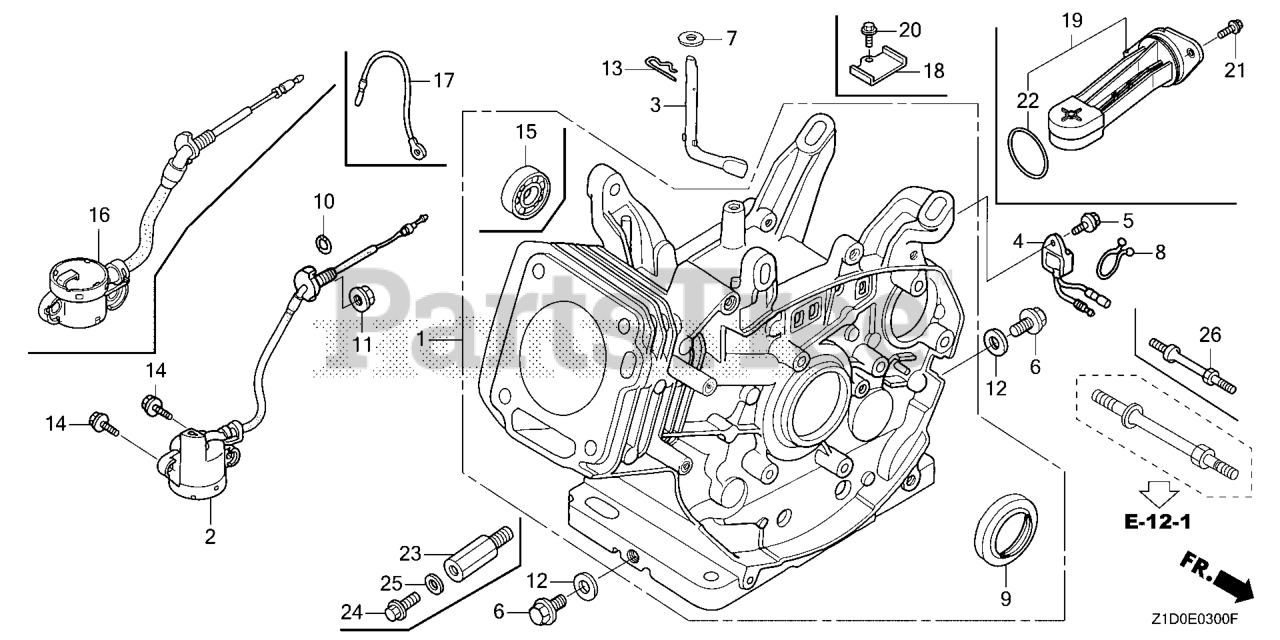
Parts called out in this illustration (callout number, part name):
1	CYLINDER ASSY.
3	SHAFT, GOVERNOR ARM
6	BOLT, DRAIN PLUG
7	WASHER (8.2X17X0.8)
9	OIL SEAL (30X46X8) (NOK ASIA)
9	OIL SEAL (30X46X8)
10	O-RING (14MM) (ARAI) Use up to Engine SN 2949254.
11	NUT, FLANGE (10MM)
12	WASHER, DRAIN PLUG (12MM)
13	PIN, LOCK (10MM)
14	BOLT, FLANGE (6X12) Use up to Engine SN 1543277.
16	SWITCH ASSY., OIL LEVEL
